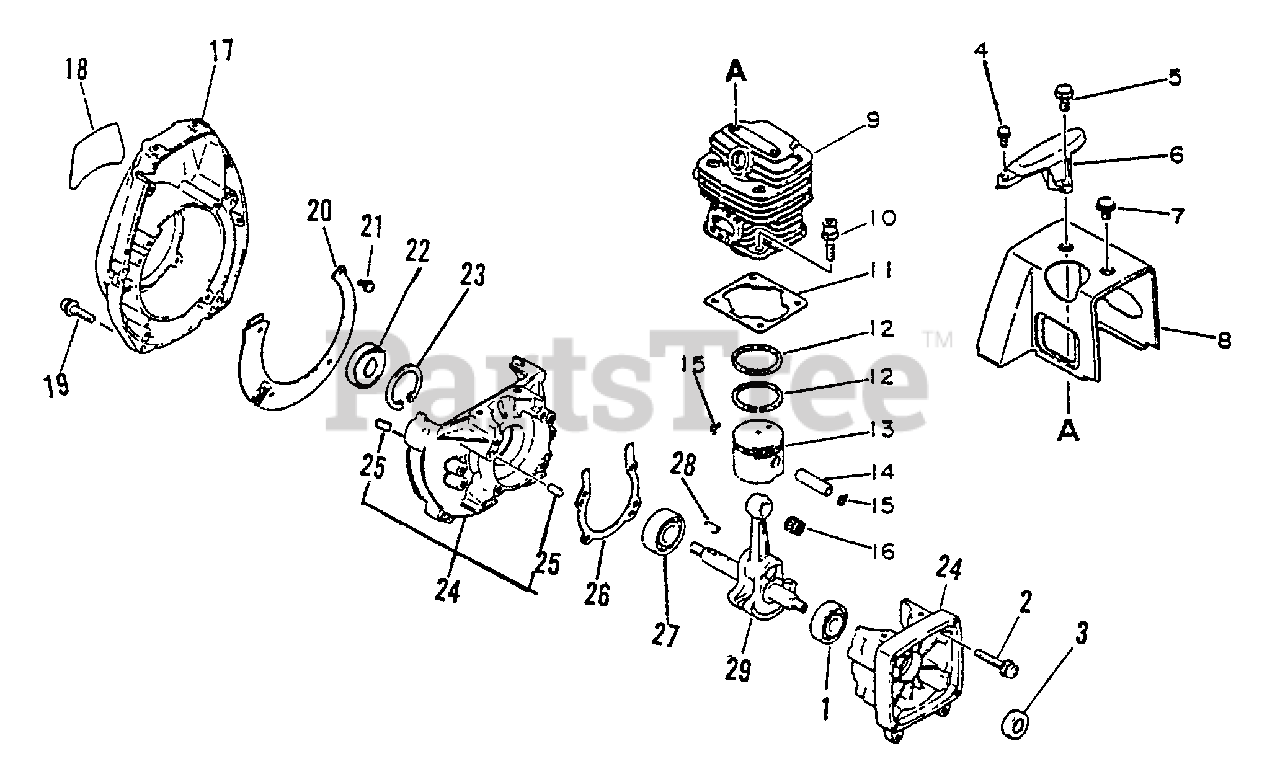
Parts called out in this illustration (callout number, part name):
1	BEARING, BALL - 6201 C3
2	SCREW 5×30
3	SEAL, OIL 12
4	SCREW 4×14
5	SCREW 5×16
6	GUARD, TOP
7	SCREW 5×10
8	COVER, ENGINE
9	CYLINDER
10	BOLT 5×20
11	GASKET, CYLINDER
12	RING, PISTON
13	PISTON
14	PIN, PISTON
15	RING, RETAINING
16	BEARING, NEEDLE 9
17	COVER, FAN
18	LABEL - MODEL
19	SCREW 5×25
20	PLATE, GUIDE
21	SCREW 4×8
22	SEAL, OIL
23	RING, SNAP 35
24	CRANKCASE KIT
25	PIN, LOCATING 5×10
26	GASKET, CRANKCASE
27	BEARING, BALL 6202
29	CRANKSHAFT
